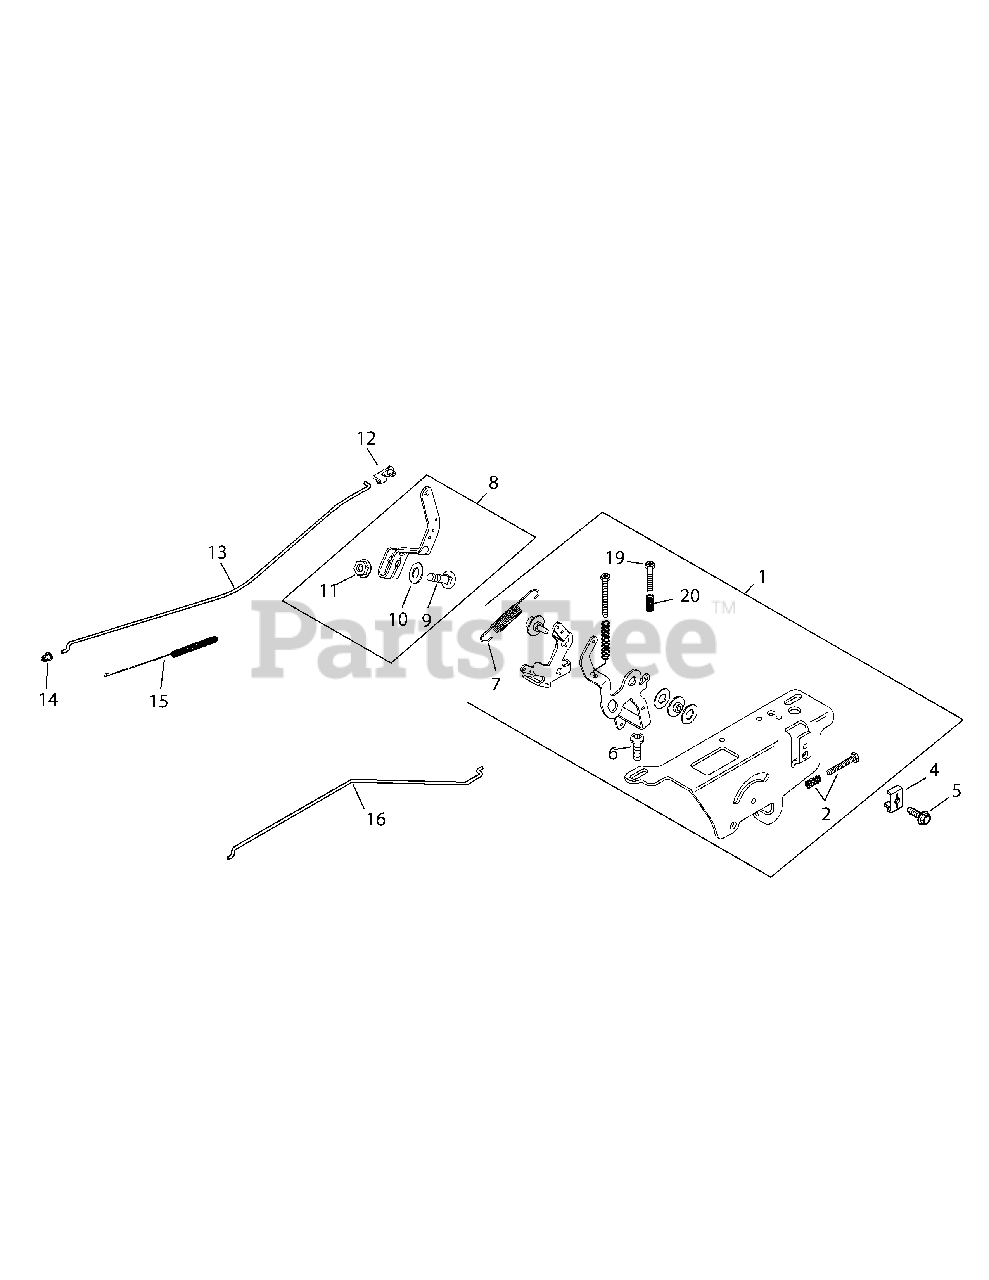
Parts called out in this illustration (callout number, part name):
1	Speed Control Assembly Kit
2	Idle Adj. Screw & Spring Kit
4	Cable Clamp
5	Flange Screw, M5 X 0.8 X 16
6	Lbd. Skt. Screw, M6 X 1.0 X 20
7	Governor Spring
8	Governor Ass’y Lever (Inc. 9-11)
9	Rd. Hd. Sq. Nck. Bolt, 1/4-20 X 1
10	Int. Tooth Lock Washer, 1/4
11	Hex Flange Nut, 1/4-20
12	Throttle Linkage Bushing
13	Throttle Linkage
14	Linkage Retaining Bushing
15	Linkage Spring
16	Choke Linkage
19	Phl. Thd. Frm. Screw, M4 X 0.7 X 25
20	Speed Control Spring (Short)
